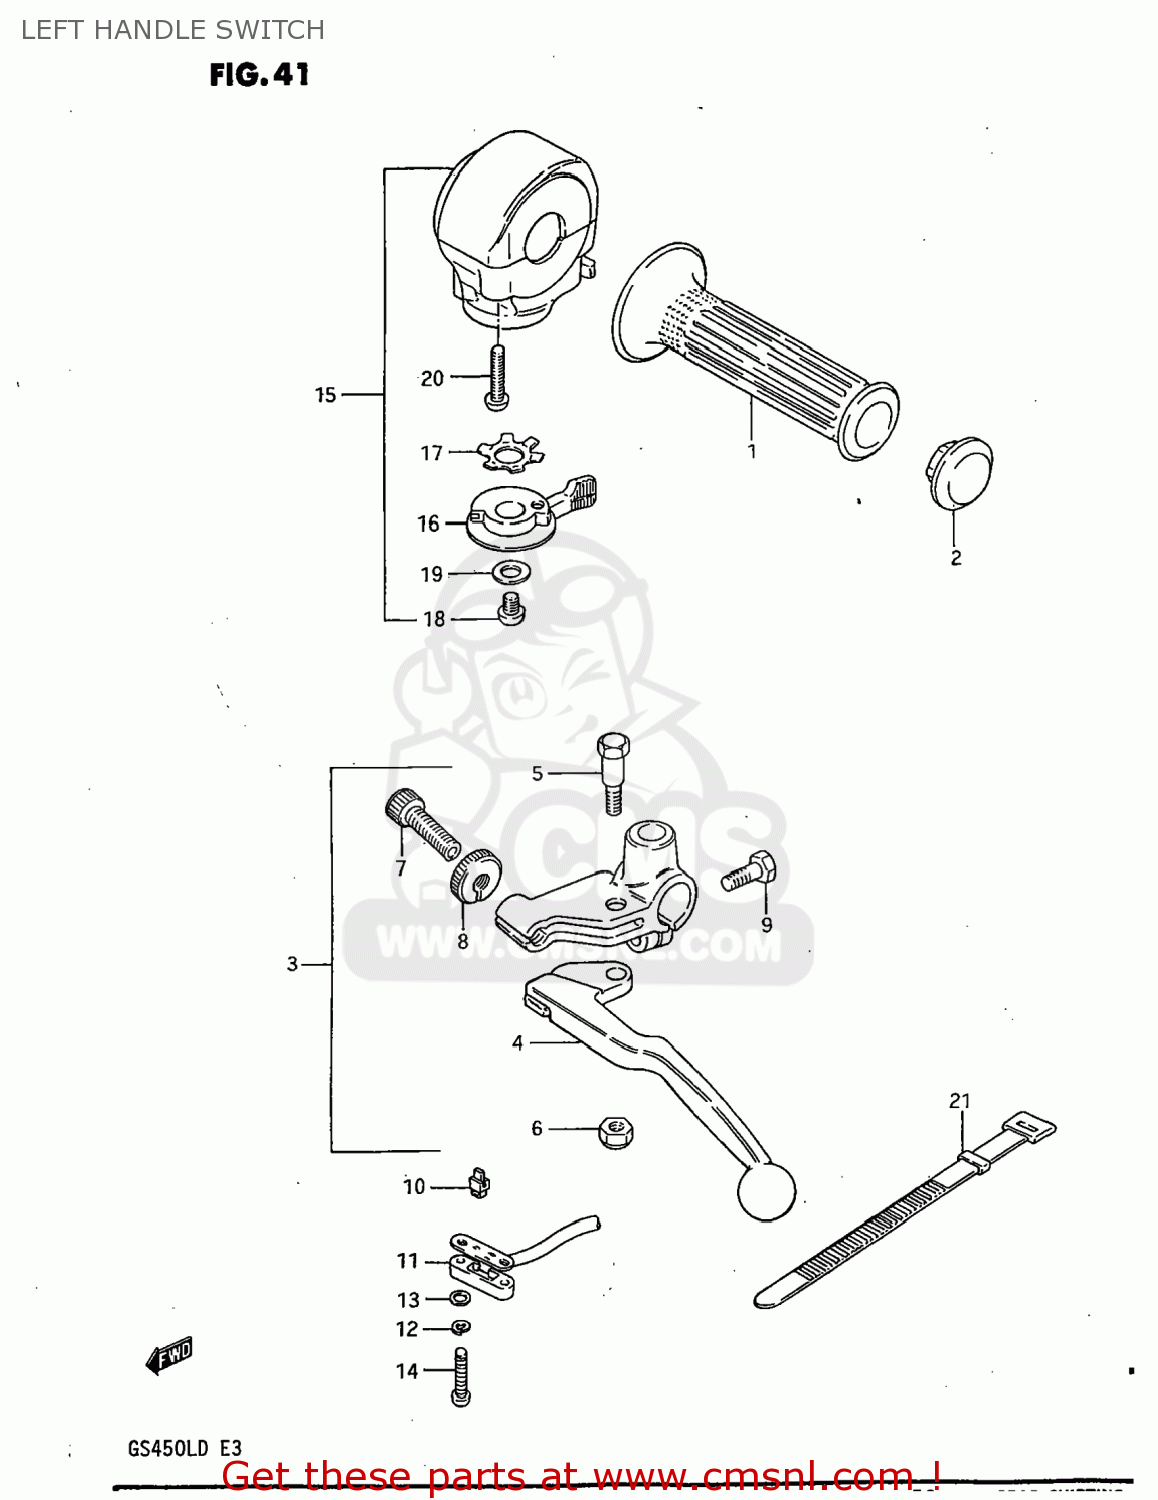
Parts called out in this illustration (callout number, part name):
1	GRIP,LEFT
2	CAP,GRIP END
3	LEVER ASSEMBLY
4	LEVER,CLUTCH
5	BOLT,LEVER
6	NUT 6MM
7	ADJUSTER,CABLE
8	NUT,CABLE ADJUSTER LOCK
9	BOLT,CLUTCH LEVER HOLDER
10	CONTACT,SWITCH
11	COVER,FR BK TERMINAL BASE
12	LOCK WASHER
13	WASHER
14	SCREW
15	SWITCH ASSEMBLY,HANDLE,LEFT
16	LEVER,STARTER
17	WASHER
18	SCREW
19	WASHER 6MM
20	SCREW
21	CLAMP(L:120)
